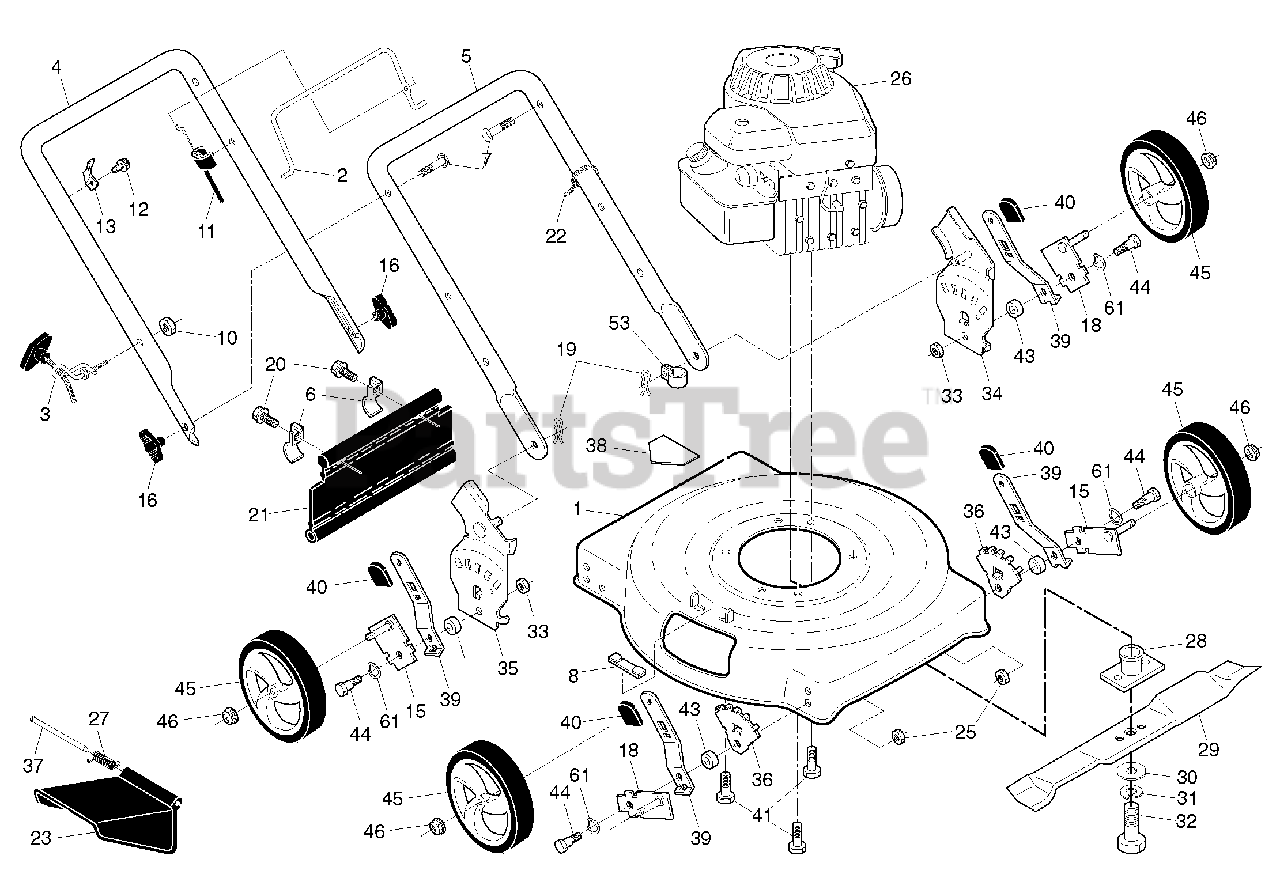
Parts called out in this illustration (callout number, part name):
1	Kit, Housing
2	Control Bar
3	Rope Guide
4	Upper Handle
5	Lower Handle
6	Bracket, Rear Skirt
7	Handle Bolt 5/16-18
8	Clip, Closeout
10	Locknut, Hex 1/4-20
11	Engine Zone Control Cable
12	Screw, Hex Head, Threaded, Rolled #10-24 x 1/2
13	Up-Stop Bracket
15	Axle Arm Assembly, Left Front & Right Rear
16	Handle Knob
18	Axle Arm Assembly, Right Front & Left Rear
19	Hairpin Cotter
20	Screw, Tapping, Hex Washer Head #10-24
21	Rear Skirt
22	Wire Tie
23	Discharge Guard
25	Nut, Hex, Flangelock 5/16-18
27	Torsion Spring
28	Blade Adapter
29	22" Blade
30	Hardened Washer
31	Helical Lockwasher 3/8
32	Screw, Hex Head, Grade 8, 3/8-24 x 1-3/8
33	Nut, Hex, Flangelock 5/16-18
34	Wheel Bracket Support (Left)
35	Wheel Bracket Support (Right)
36	Wheel Bracket Adjuster
37	Hinge Rod
38	Danger Decal
39	Selector Spring
40	Selector Knob
41	Screw, Hex Head, Threaded, Rolled 3/8-16 x 1
43	Spacer
44	Shoulder Bolt 5/16-18 x .33
45	Wheel & Tire Assembly
46	Nut, Hex, Flangelock 3/8-16
53	Clip, Cable
61	Washer, Curved, Cylindrical
